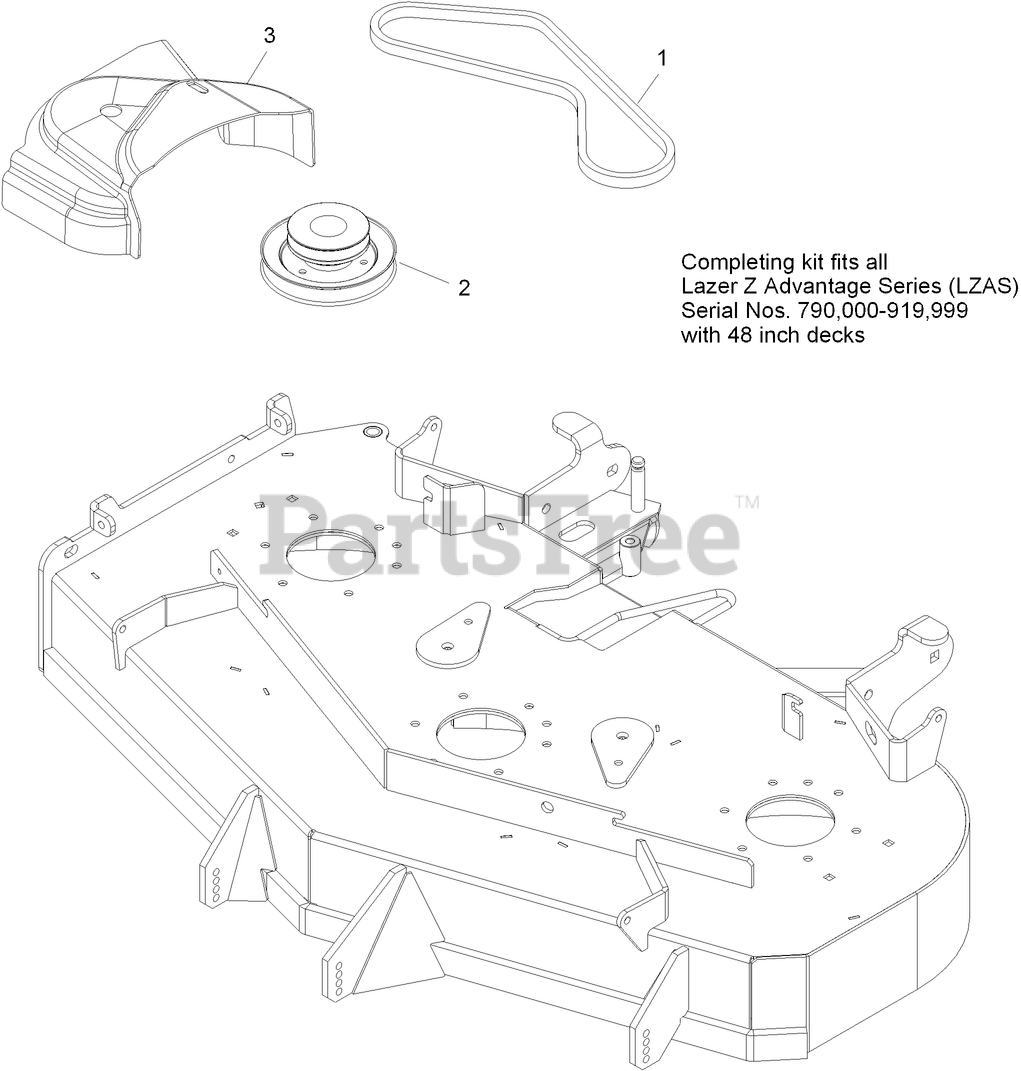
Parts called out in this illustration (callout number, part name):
1	BELT-BLOWER
2	JACKSHAFT,UV DRIVE 484
3	COVER,BELT UV 48
